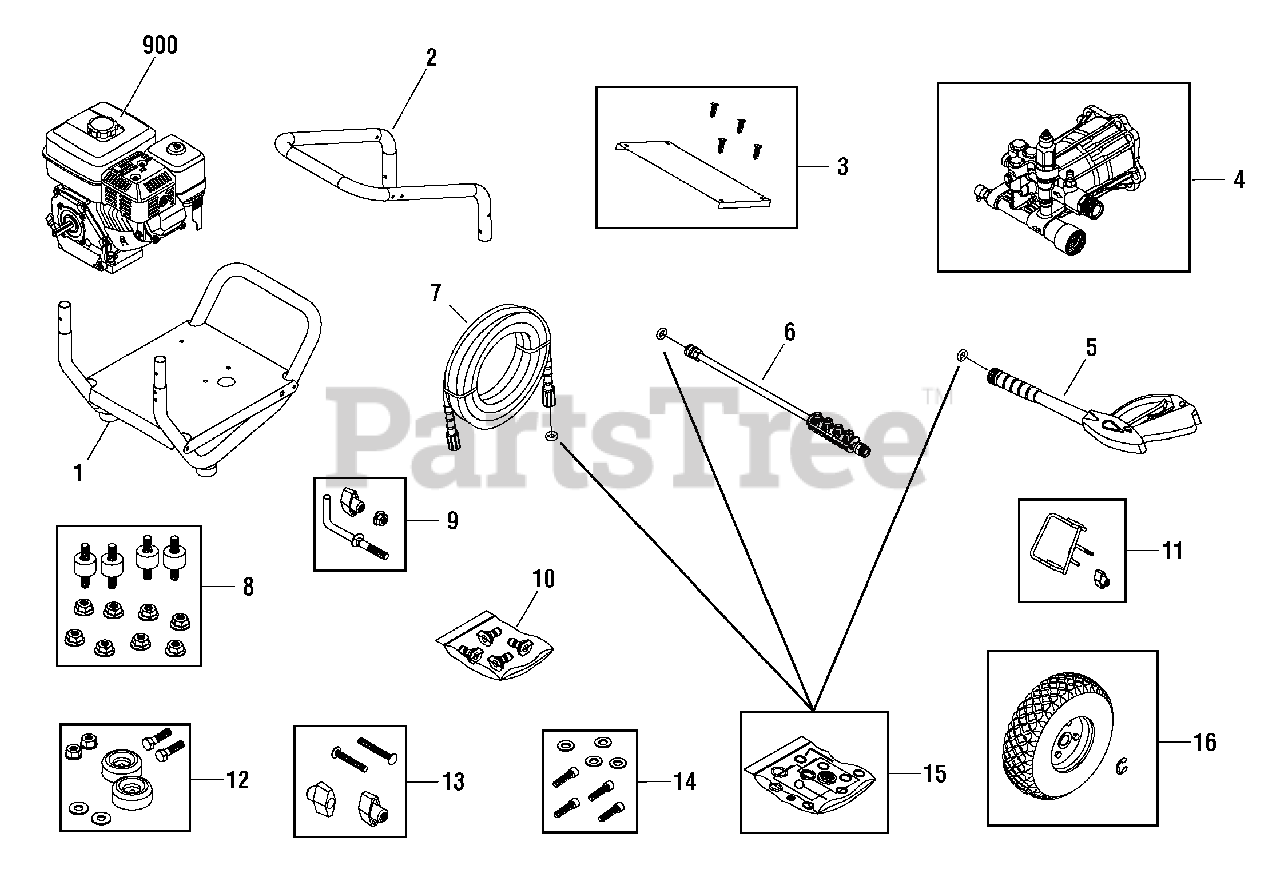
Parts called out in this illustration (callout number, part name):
5	GUN
6	EXTENSION, QC
7	HOSE
8	KIT, Vibration Mount
10	KIT, QC Nozzles
12	MOUNT, Vibration
13	KIT, Hardware, Handle
14	KIT, Hardware, Pump Mounting
15	KIT, O-Ring
900	* ENGINE
